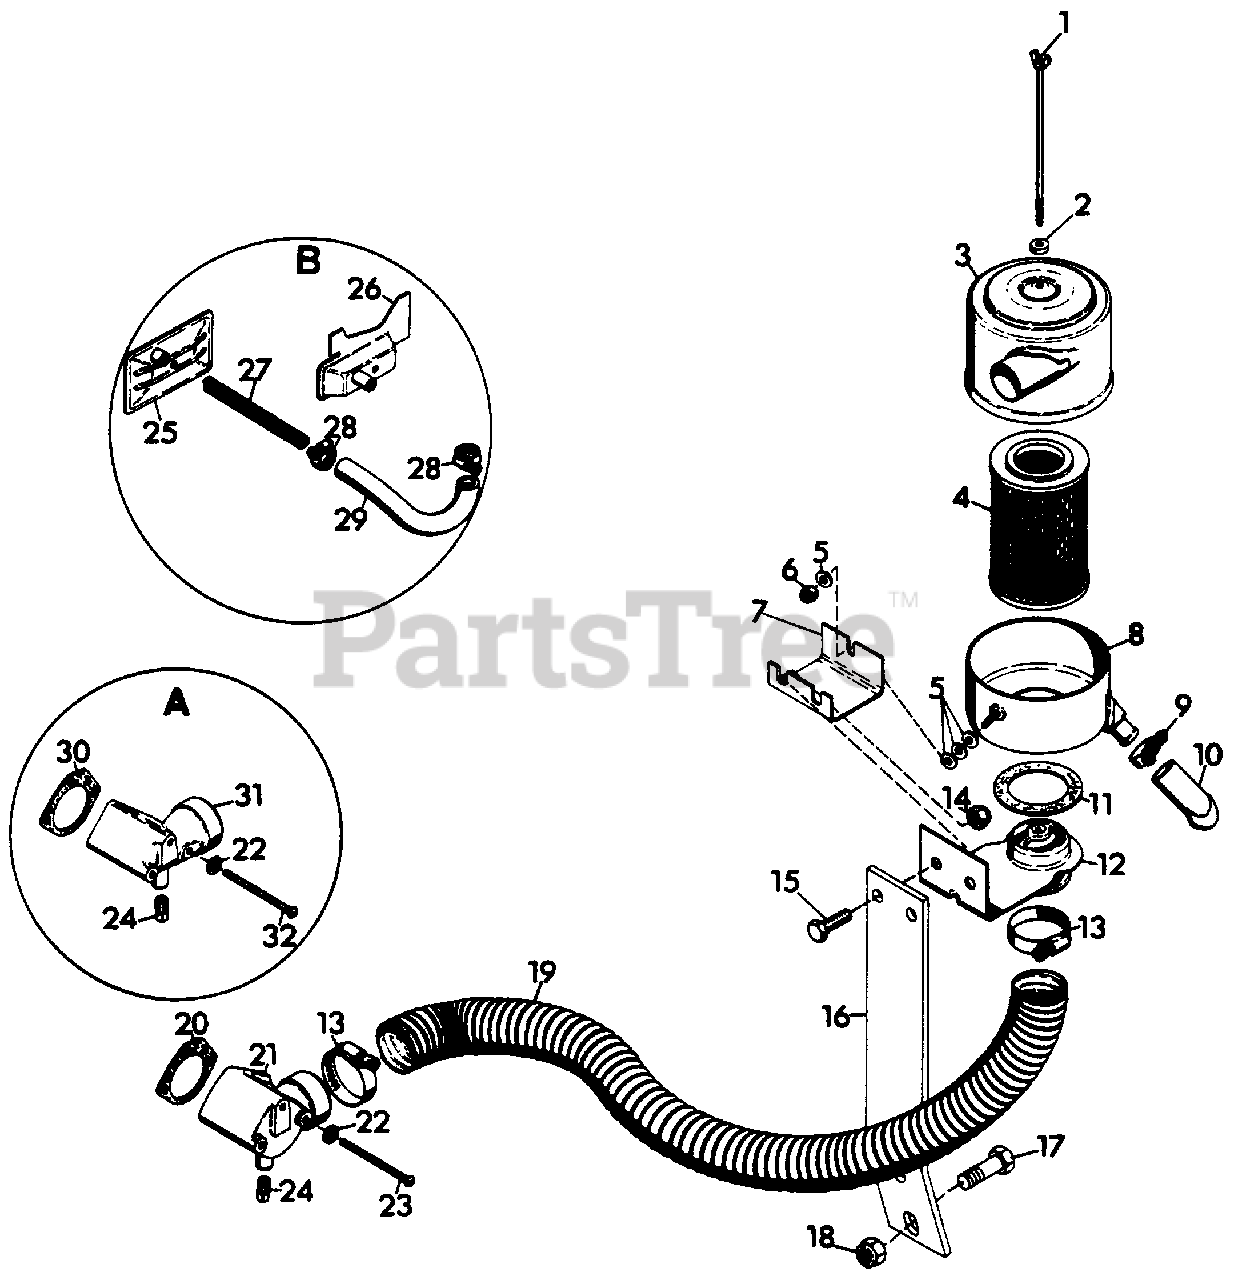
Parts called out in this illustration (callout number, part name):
1	BOLT, SPECIAL AIR CLEANER
2	WASHER, SEALING
3	HOUSING, UPPER
4	FILTER, ELEMENT
5	WASHER, FLAT .281X.625X.065
6	NUT, LOCK 1/4-20
7	SUPPORT, REMOTE AIR CLEANER
8	HOUSING, LOWER
9	CLAMP, AIR CLEANER
10	UNLOADER, DUST
11	GASKET, AIR CLEANER
12	BRACKET, AIR CLEANER
13	CLAMP, 2.25 DIA. HOSE
14	NUT, LOCK 3/8-16
15	BOLT, HEX 3/8-16X1.125
16	BRACKET
17	BOLT, HEX 1/2-13X1.50
18	NUT, LOCK 1/2-13
19	HOSE, AIR CLEANER
20	GASKET, AIR CLEANER ELBOW
21	ASSEMBLY, ELBOW AIR CLEANER
22	WASHER, COPPER .219X.500X.049
23	SCREW, MACHINE 10-32X3 PHD
24	PLUG, PIPE 1/8 SQ. HD. STL.
25	PLATE, BREATHER
26	PLATE BREATHER
27	SPRING, HOSE
28	CLAMP, .88 DIA. HOSE
29	HOSE, CRANKCASE VENTILATION
30	GASKET, AIR CLEANER ELBOW
31	ASSEMBLY, AIR CLEANER ELBOW
32	SCREW, MACHINE 8-32X2.75 PHD
